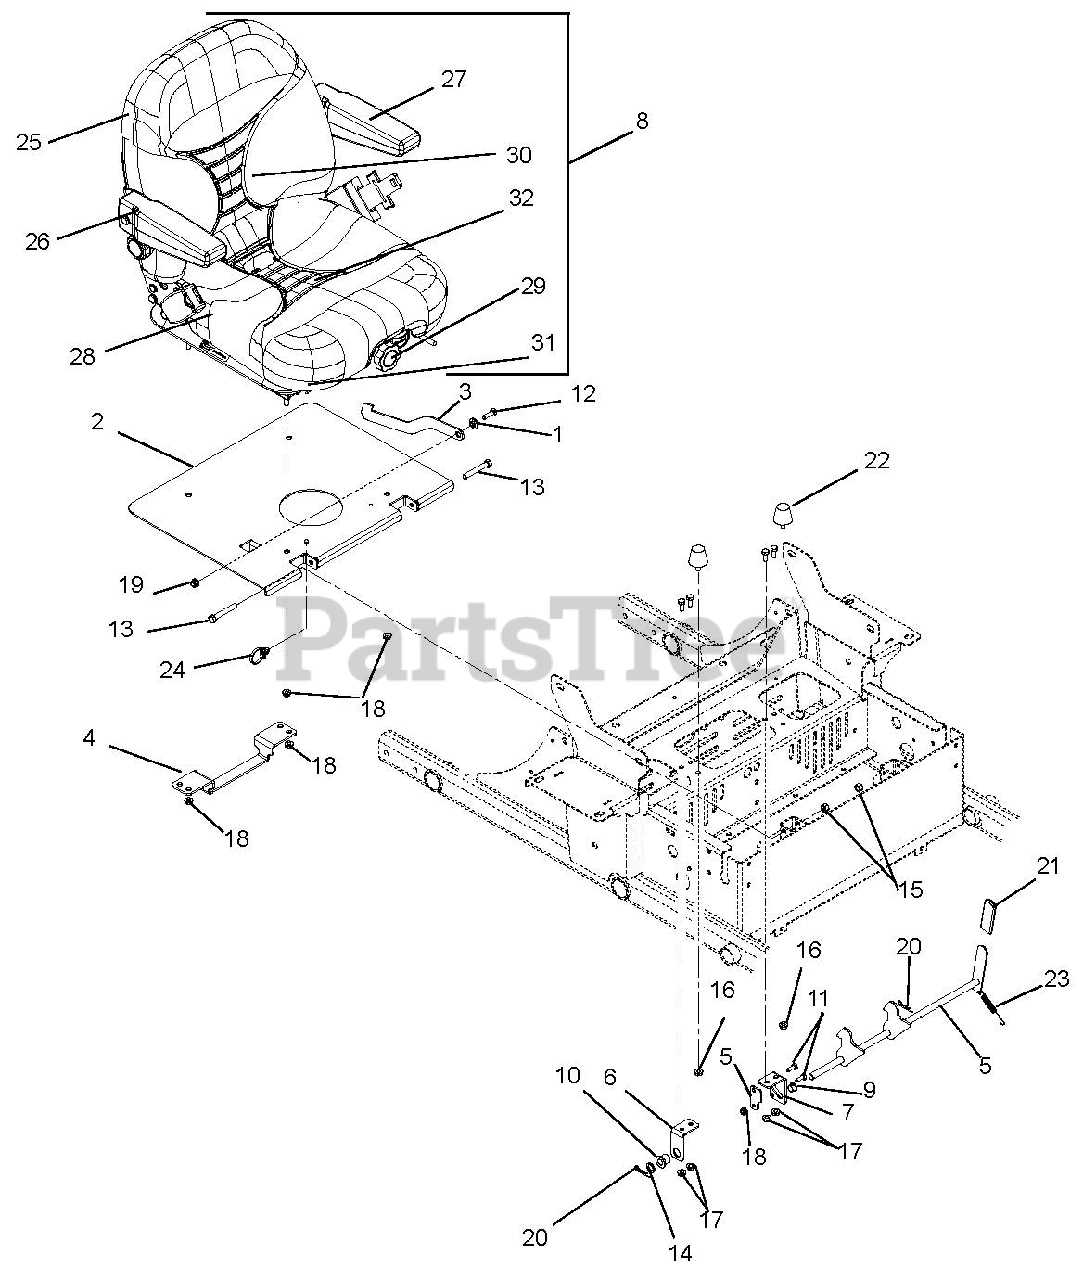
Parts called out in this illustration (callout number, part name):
1	Bushing, Flange .325 x .499 x .26 x .88
2	Seat Plate Weldment – Black
3	Stop, Seat Pivot
4	Bracket, Seat Latch
5	Weldment, Seat Latch
6	Mount, Seat Latch – Right Hand
7	Mount, Seat Latch – Left Hand
8	Seat, SUSP, with Seat Belt, Light Gray
9	Bushing, Polyliner – .50 Split
10	Bushing, Flange .515 x .750 x .745 x 1.00NY
11	Bolt, Hex .25-20 x .75 GR5 YWZC
12	Bolt, Hex .31-18 x .75 GR5 YWZC
13	Bolt, Hex .38-16 x 2.50 GR5 YWZC
14	Washer, Flat Steel .52 x .827 x .062 YWZC
15	Nut, Locking Center .38-16 YWZC
16	Nut, Spin Lock Flange .312-18 YWZC
17	Nut, Locking Top Flange .31-18 YWZC
18	Nut, Locking Top Flange .25-20 YWZC
19	Nut, Locking Nylon Flange .31-18 YWZC
20	Pin, Hair Internal .08 x .38 x 1.42 YWZC
22	Bumper, Rubber Cone, Stud Mount
23	Spring, Tension .043 x .44 x 3.31 WLD 5.8
24	Cable Tie with Tree (.25 HOLE)
25	Kit, Back Cushion, Light Gray
26	Kit, Armrest Assembly – Right Side
27	Kit, Armrest Assembly – Left Side
28	Kit, Seat Cushion, Light Gray
29	Kit, Seat Knobs
30	Kit, Seat Back
31	Kit, Seat Slides
32	Kit, Seat, Spring and Saddle
